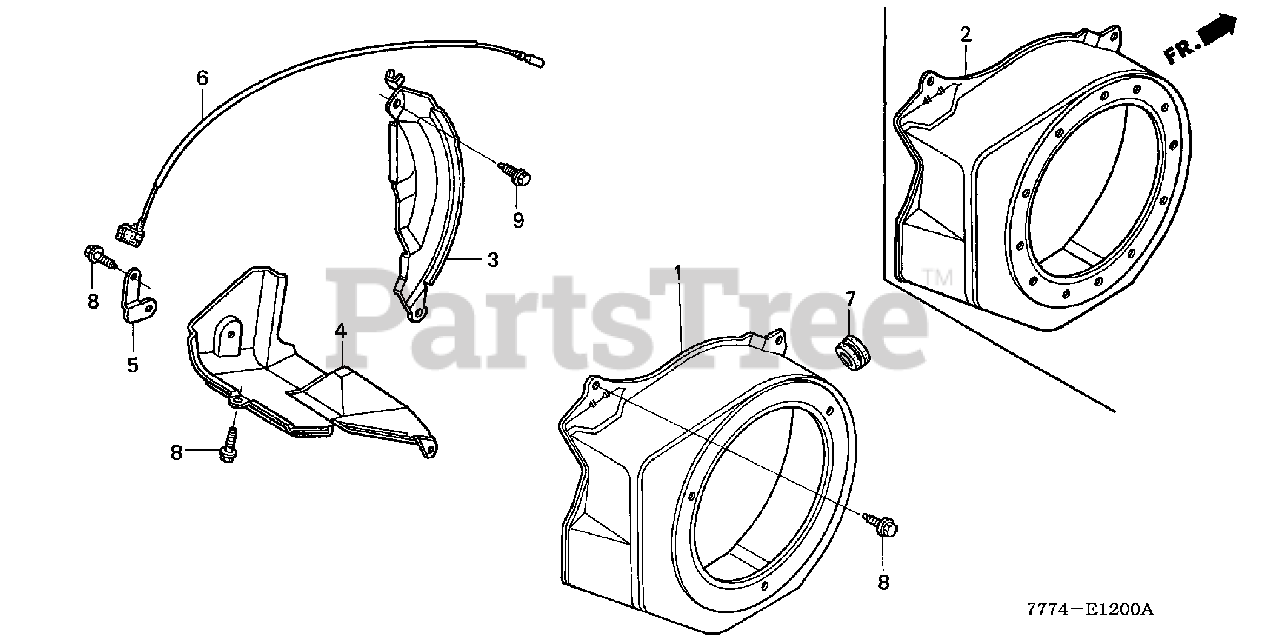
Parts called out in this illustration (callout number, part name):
1	COVER, FAN *R8* (BRIGHT RED)
1	COVER, FAN *R280* (POWER RED)
3	PLATE, SIDE (STD)
4	SHROUD
5	STAY, WIRE CLIP
6	WIRE, STOP SWITCH (370MM)
7	GROMMET, DRAIN HOLE
8	BOLT, FLANGE (6X12) (CT200)
9	BOLT, FLANGE (6X20) (CT200)
